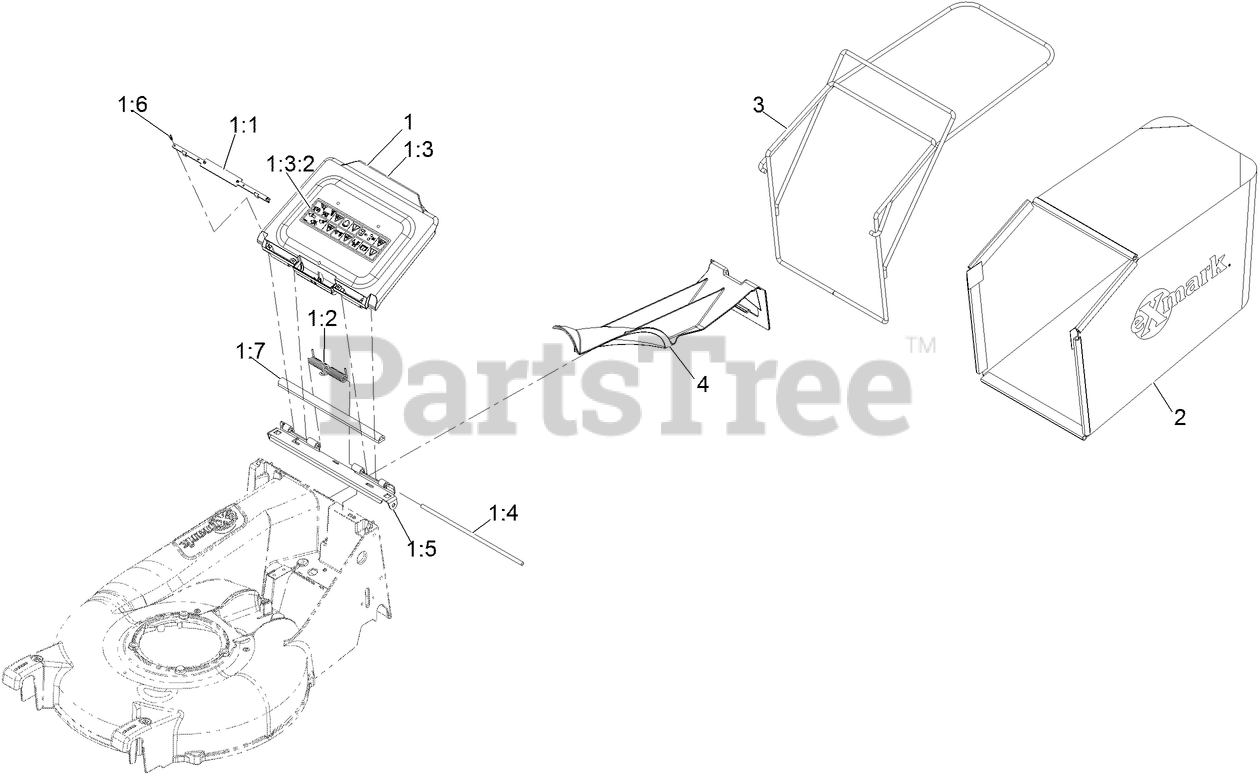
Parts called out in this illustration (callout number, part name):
1	DOOR ASM
1:1	X-REF 126-2628-03
1:2	SPRING-PLASTIC DOOR
1:3	ASM-DOOR & DECAL
1:3:2	DECAL-WARNING
1:4	PIN-DOOR PIVOT
1:5	X-REF TO 126-2636-03
1:6	SCR,TAP,6-19X7/16,PHPH, S
1:7	SEAL-EPDM FOAM BULB
2	BAG-GRASS EC21
3	WLD-BAG FRAME
4	PLUG,MULCH
